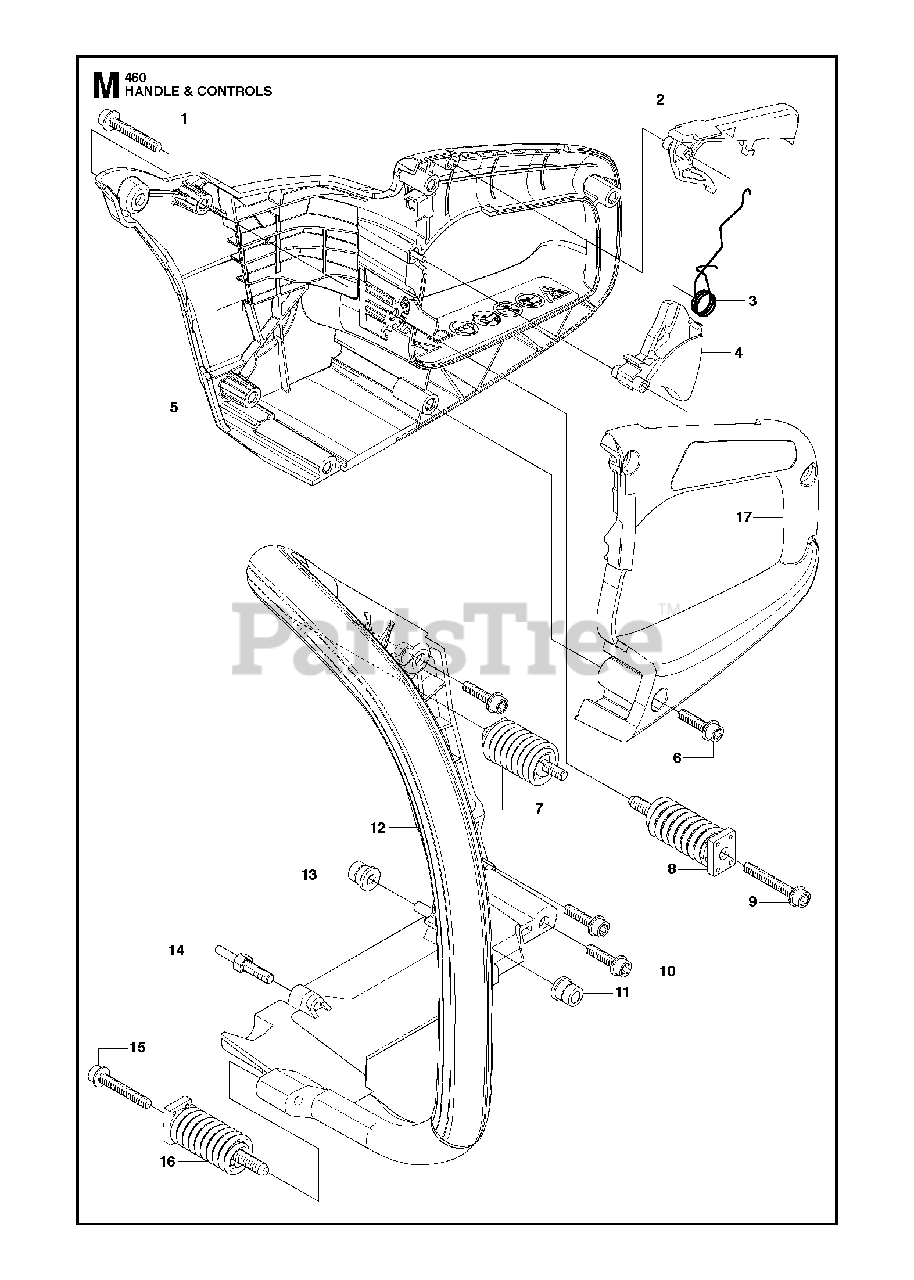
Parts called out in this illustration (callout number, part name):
2	THROTTLE LOCK
4	THROTTLE TRIGGER
5	REAR HANDLE
7	VIBRATIONS ABSORBER
8	VIBRATION ABSORBER
11	MOVEMENT LIMITER
12	FRONT HANDLE
13	MOVEMENT LIMITER
17	CAP - LEFT SIDE HANDLE
